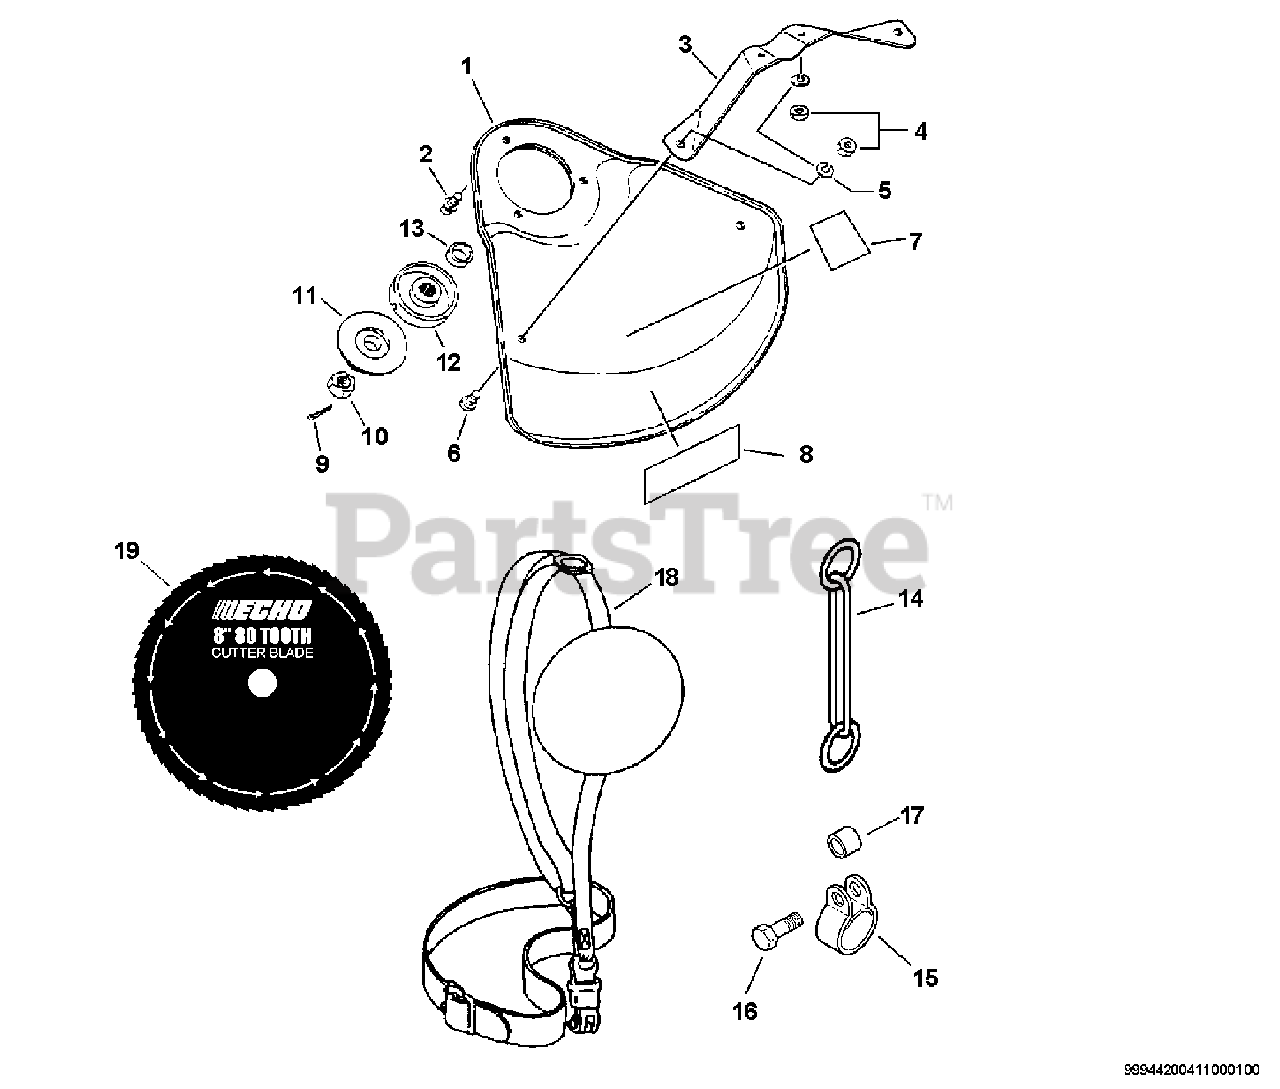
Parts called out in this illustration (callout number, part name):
1	SHIELD, DEBRIS - METAL
2	SCREW - 5X10
3	BRACKET, SHIELD
5	LOCKWASHER - 5
6	SCREW - 5X8
7	LABEL - CAUTION
8	LABEL - ECHO
9	PIN, SPLIT - 2X22
10	NUT - 10 -- LEFT HAND
11	ADAPTOR, BLADE - LOWER
12	ADAPTOR, BLADE - UPPER
16	BOLT - 5X18
18	SHOULDER STRAP ASSY
19	BLADE - 80 TOOTH -- 8" (20cm)
